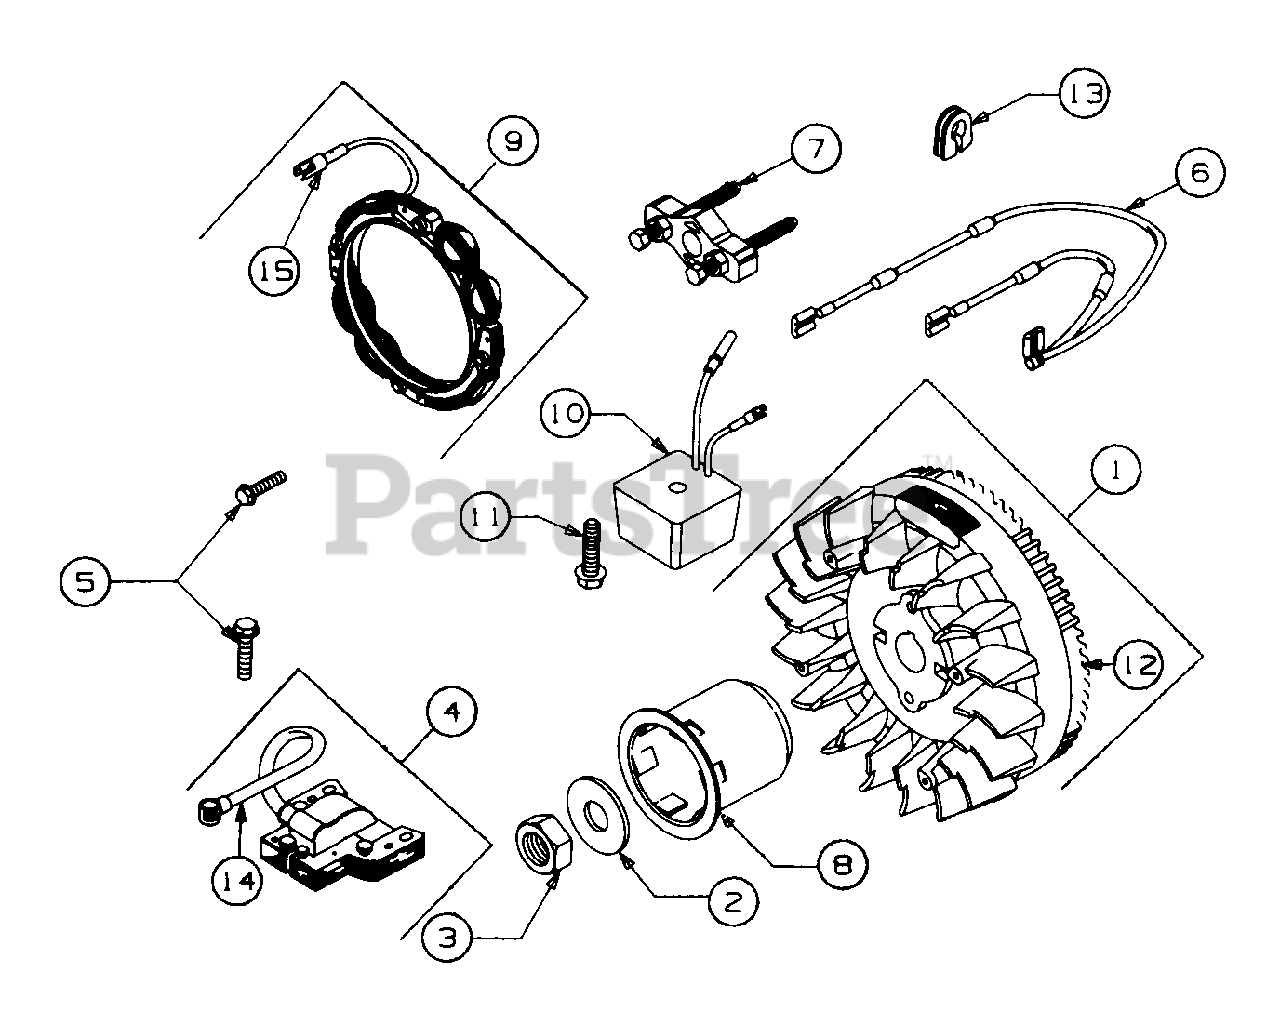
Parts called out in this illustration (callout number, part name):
1	Flywheel, Magneto
2	Washer, Spring
4	Armature, Magneto
5	Screw, Mounting
6	Wire Assy
7	Puller, Flywheel
8	Hub, Starter
9	Stator, Alternator
10	Regulator, Alternator
11	Screw, Hex Head
12	Gear, Ring
13	Grommet
14	Terminal, Ignition Cable
15	Connector Assy
